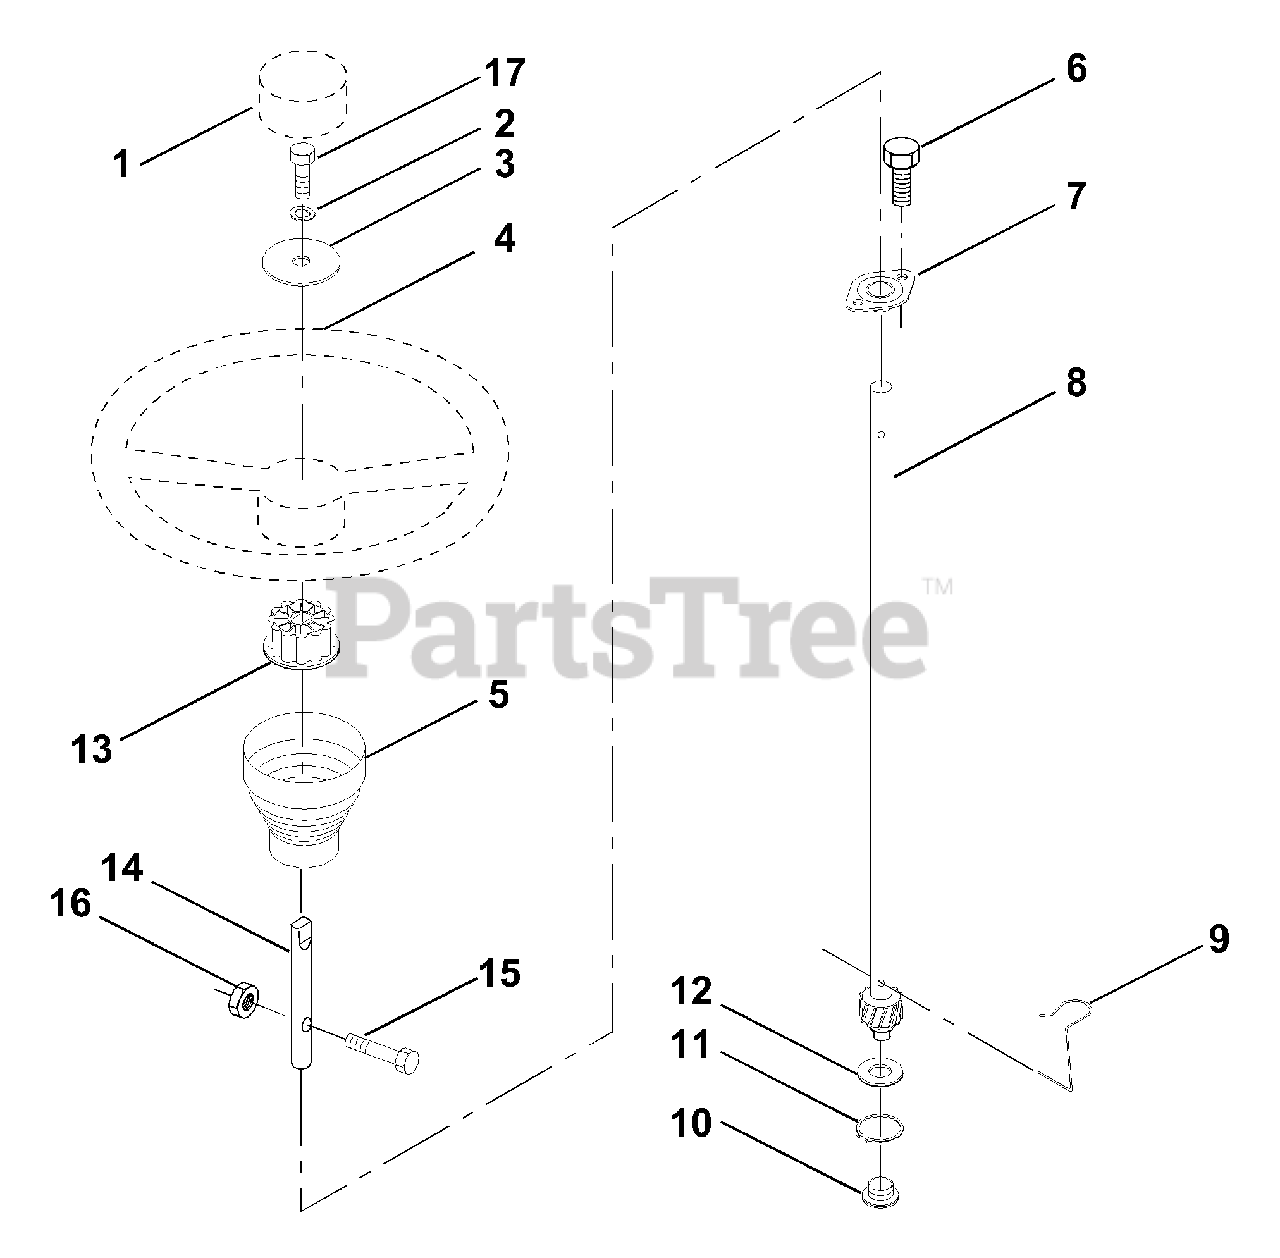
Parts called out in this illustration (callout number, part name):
1	Insert, Wheel, Steering
2	Washer, Lock hvy HLCL SPR 3/8
3	Washer 12/32 x 2-3/8 x 8 Ga.
4	Wheel, Steering
5	Sleeve, Steering
6	Screw, TT #10-32.5.3/8 flange
7	Bushing, Steering
8	Shaft, Steering
9	Clip, Steering
10	Bushing, Lower, Steering
11	Ring, Retaining
12	Washer 21/32 x 1 x 16 Ga.
13	Adaptor, Wheel, Steering
14	Extension shaft steering
15	Bolt Fin Hex 5/16-18 UNC x 1-1/4
16	Nut Lock Hex W/Ins. 5/16-18 UNC
17	Bolt fin Hex 3/8-16 UNC x 1. Gr. 5
